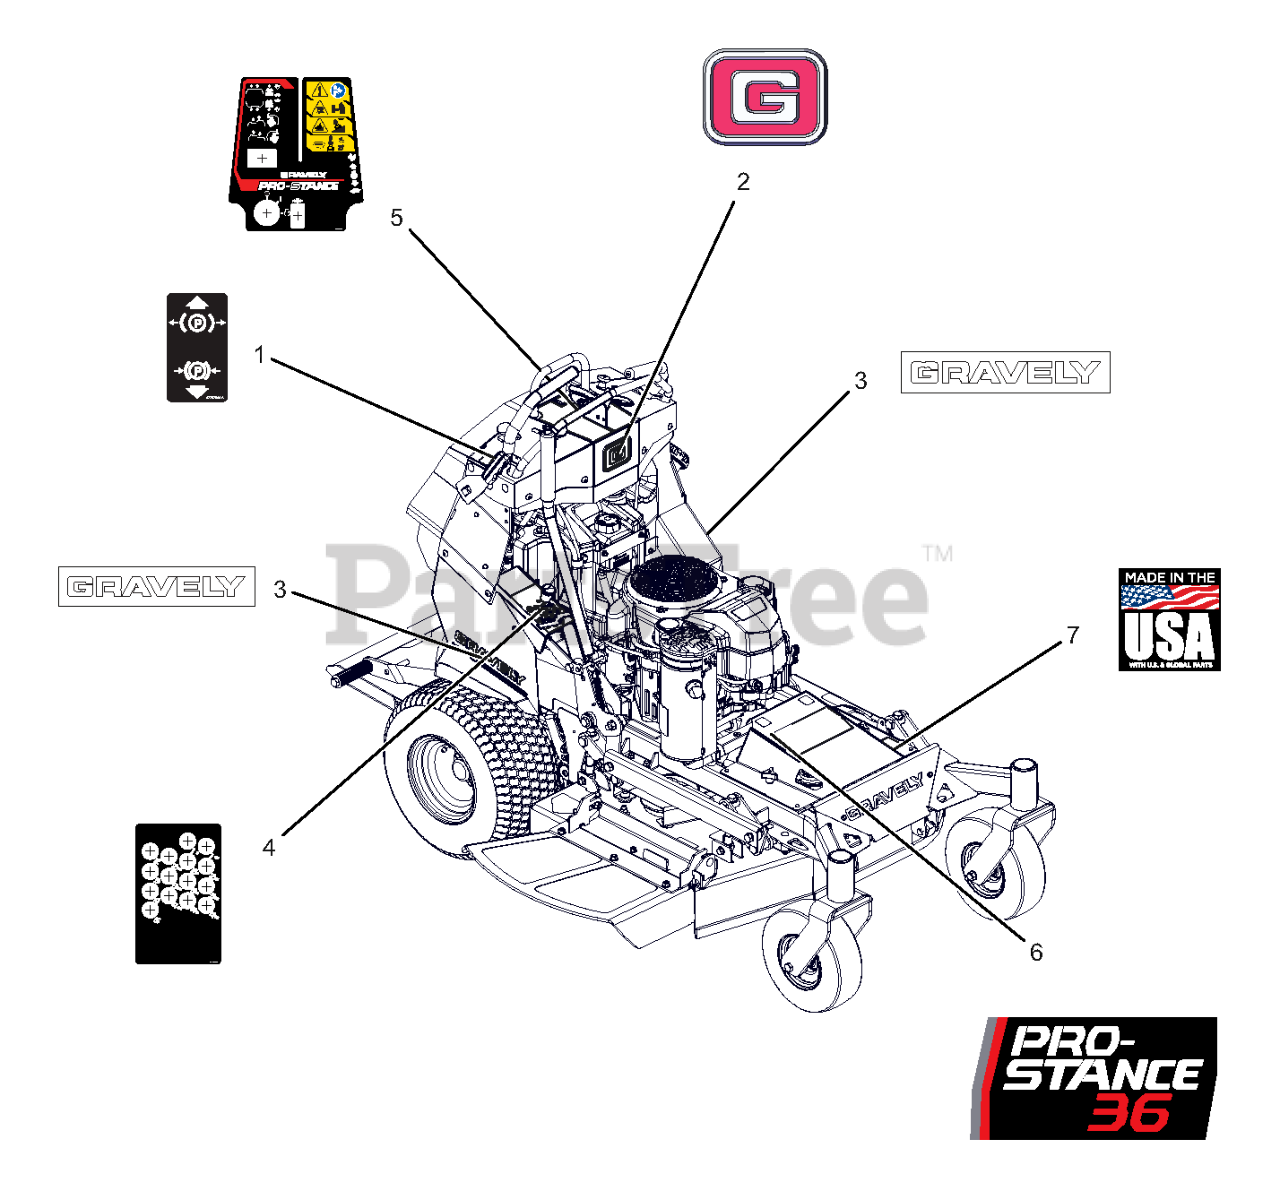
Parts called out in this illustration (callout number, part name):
1	DECAL, PARKING BRAKE LEVER
2	DECAL, GRAVELY BRAND
3	DECAL, 9.5" GRAVELY LOGO
4	DECAL, PRO STANCE - 32-36 HOC
5	DECAL, DASH - PROSTANCE
6	DECAL, PROSTANCE 36
7	DECAL, MADE IN USA
